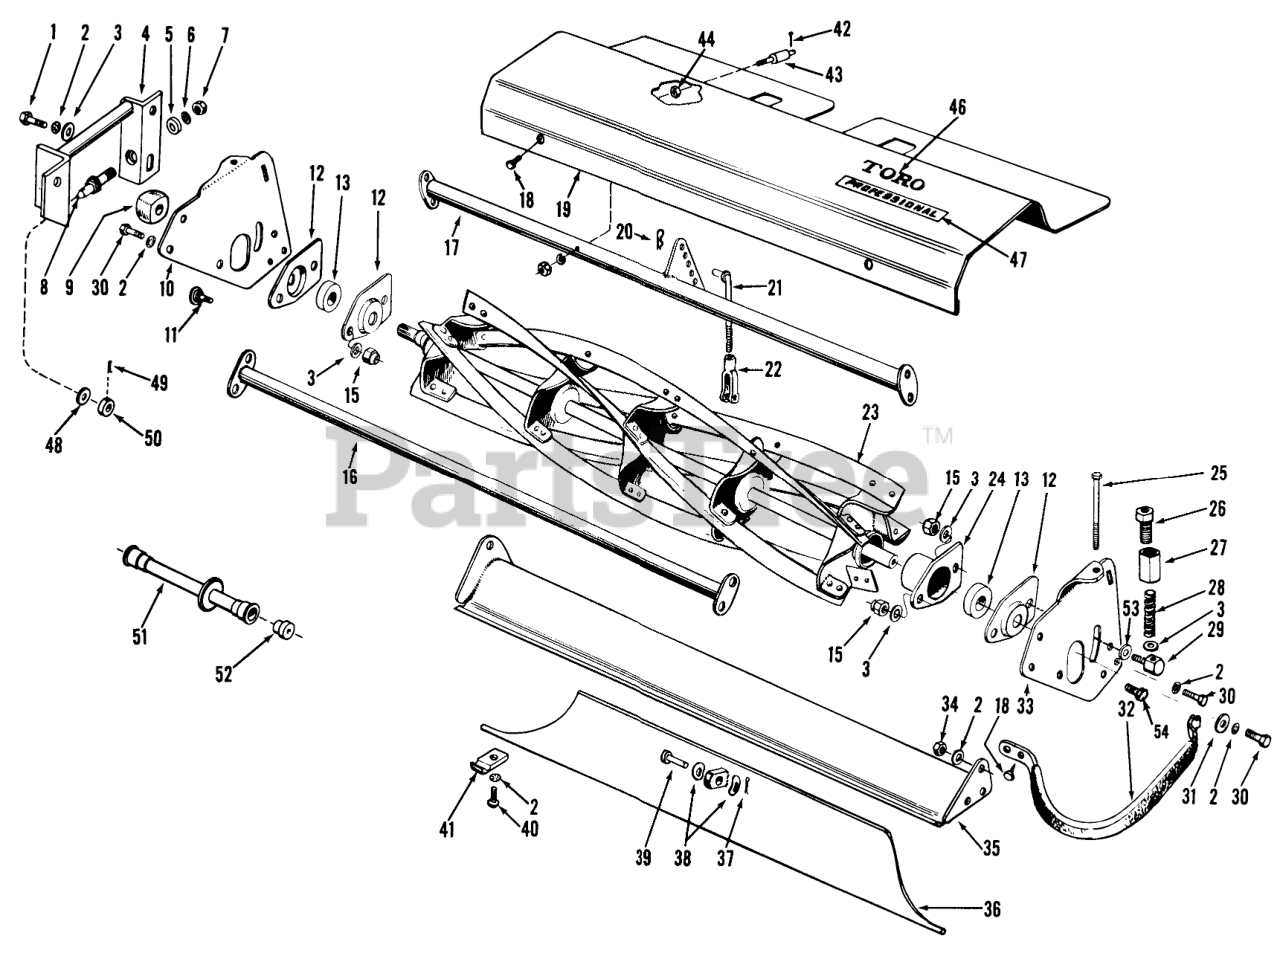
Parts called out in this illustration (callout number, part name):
1	SCREW-HH
2	WASHER-LOCK, INTERNAL
3	WASHER-PLAIN
5	SPHERICAL SPACER
6	WASHER-LOCK
7	NUT-HEX
11	BEARING CUP BOLT
15	NUT-LOCK
18	10-16 X 3/8 THDG SCREW
20	PIN-COTTER
22	YOKE
26	Bolt-Adjusting
27	ADJUSTMENT BLOCK
29	REEL BEARING SCREW
30	SCREW-HH
31	WASHER-FLAT
34	NUT-HEX
37	PIN-COTTER
38	WASHER-SPRING
39	PIN-CLEVIS
41	CLIP-SKID
42	PIN-COTTER
47	Decal
48	9/16ID X 032 WASHER
49	PIN-COTTER
50	COLLAR
53	WASHER
54	SCREW-HH
